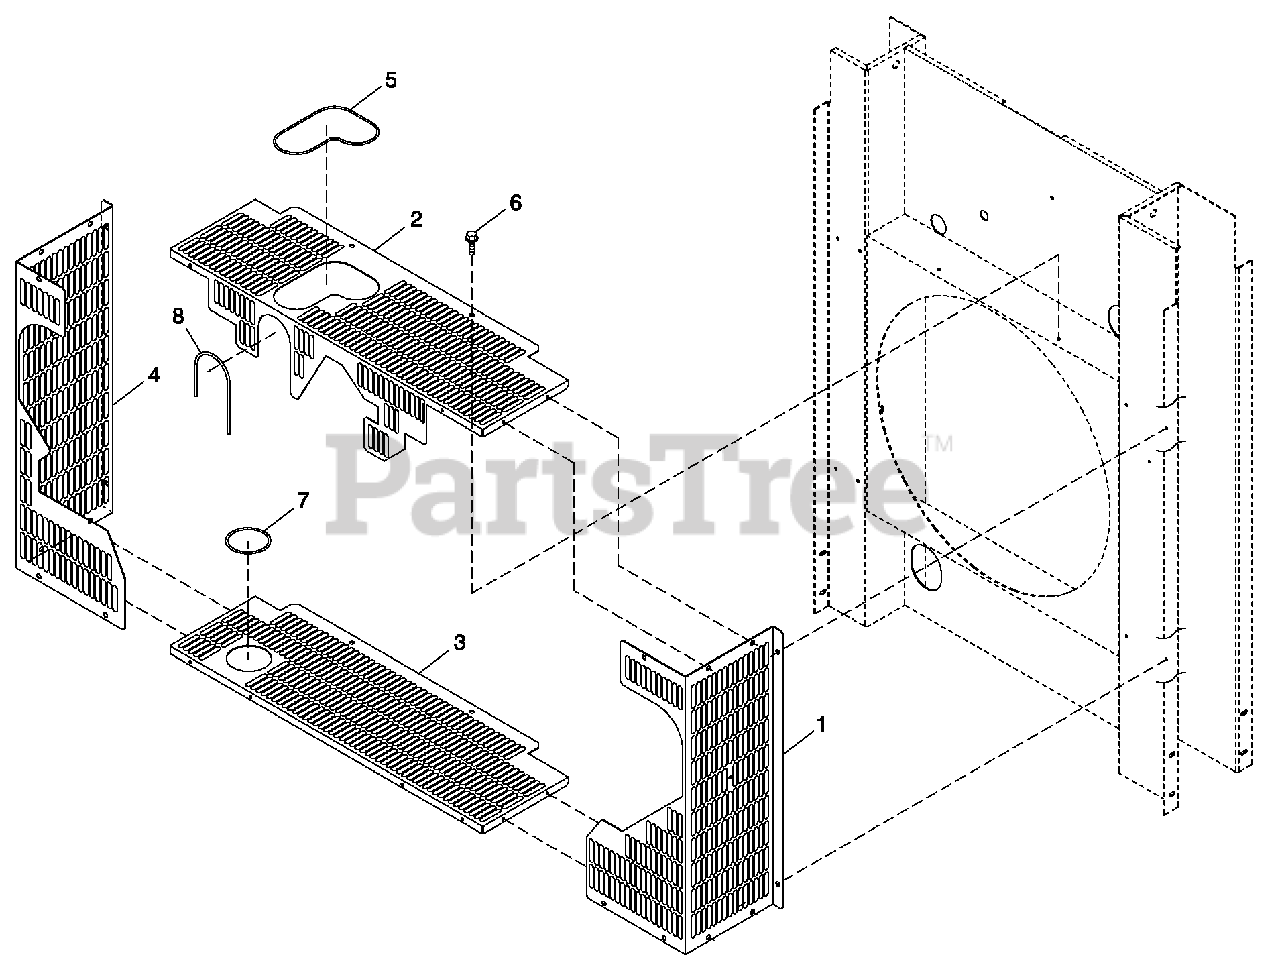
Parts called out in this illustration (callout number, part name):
1	GUARD BELT RIGHT HAND C3
2	GUARD BELT TOP C3
3	GUARD BELT BOTTOM C3
4	GUARD BELT LEFT HAND C3
5	TRIM VINYL BLACK 1/8GP (21" LG)
6	SCREW THF M6-1 X 16 N WA Z/JS
7	TRIM VINYL BLACK 1/8GP (10 .37" LG)
8	TRIM VINYL BLACK 1/8GP (12" LG)
